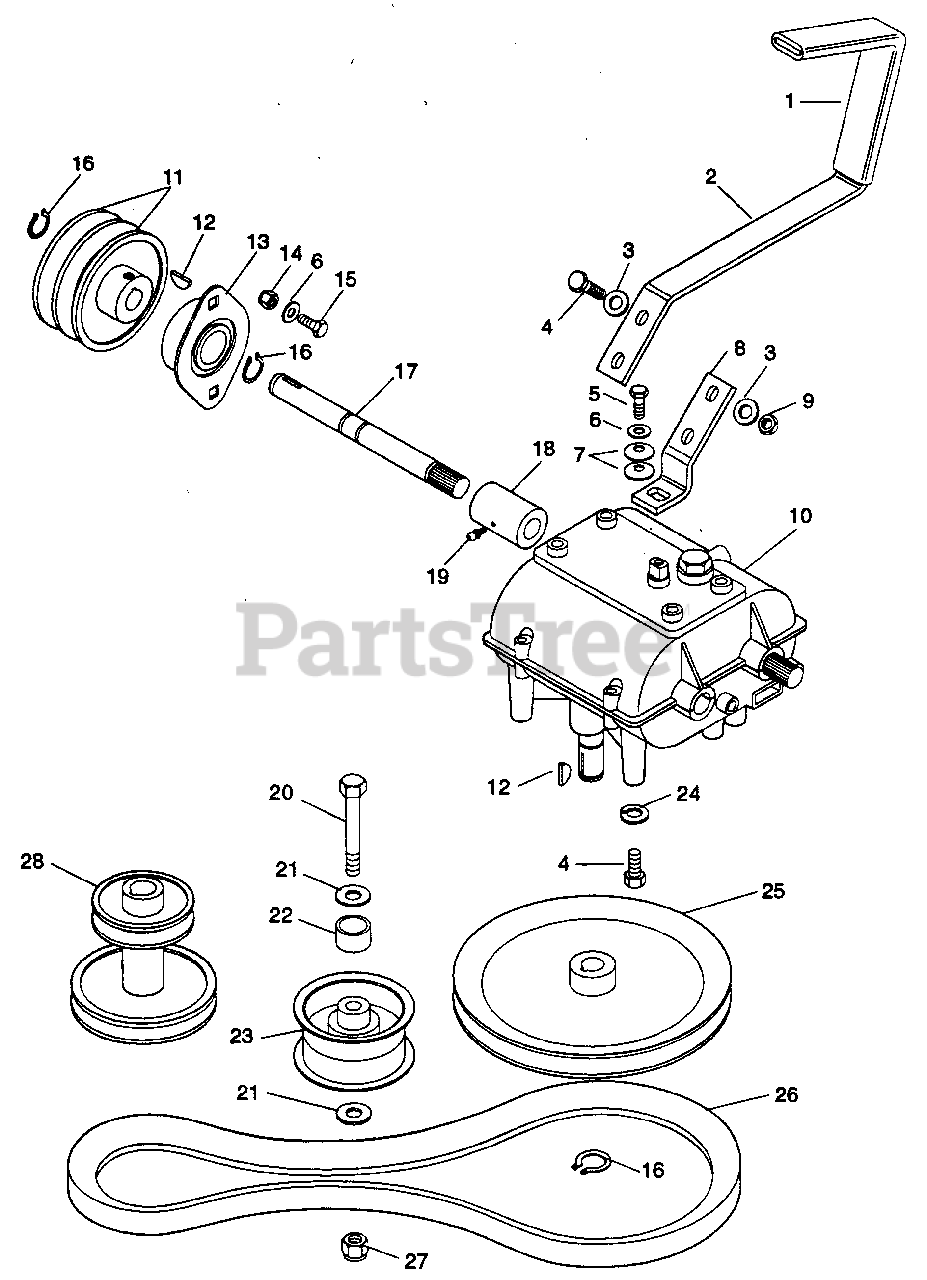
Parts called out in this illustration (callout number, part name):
1	GRIP
2	LVR, TRANS SHIFT
3	WSHR-FL-STL .344 X .688 X .065
4	BLT-HEX .31-18 X 1.00 PL GR 5
5	BLT-HEX .25-28 X .75 HEX PL GR 8
6	WSHR-FL-STL .281 X .62 X .065 PL
7	WSHR, BELLEVILLE
8	ARM, TRANS SHIFT
9	NUT-LK-NYL .312-18 PL
10	TRANS, 5-SPEED PRO 32
11	DRIVE SHEAVE(UPPER) - PRO-150
12	KEY, WDRF .19 X .75 HRD #9
13	BRG-FLG .625 X 1.875 X .797
14	NUT-LK-NYL .250-20 PL
15	BLT-HEX .25-20 X .75 PL GR 5
16	RG-RTNG-EXT .579 X .93
17	HALF SHAFT, TRANS, PRO-150
18	COUPLER, TRANS SHAFT
19	FTG-LUBE .25-28 X .256
20	BLT-HEX .38-16 X 2.25 GR 5
21	WSHR-FL-STL .406 X .812 X .065 PL
22	SPCR, .625 X .385 X .55
23	IDLER-PLY
24	WSHR-LOCK .313 X .078 PL
25	PLY-V 7.50 X .626
26	V-BELT A-RMA 14.9 X 33/64
27	NUT-LK-NYL .375-16 PL
28	CRANK SHEAVE-PRO
